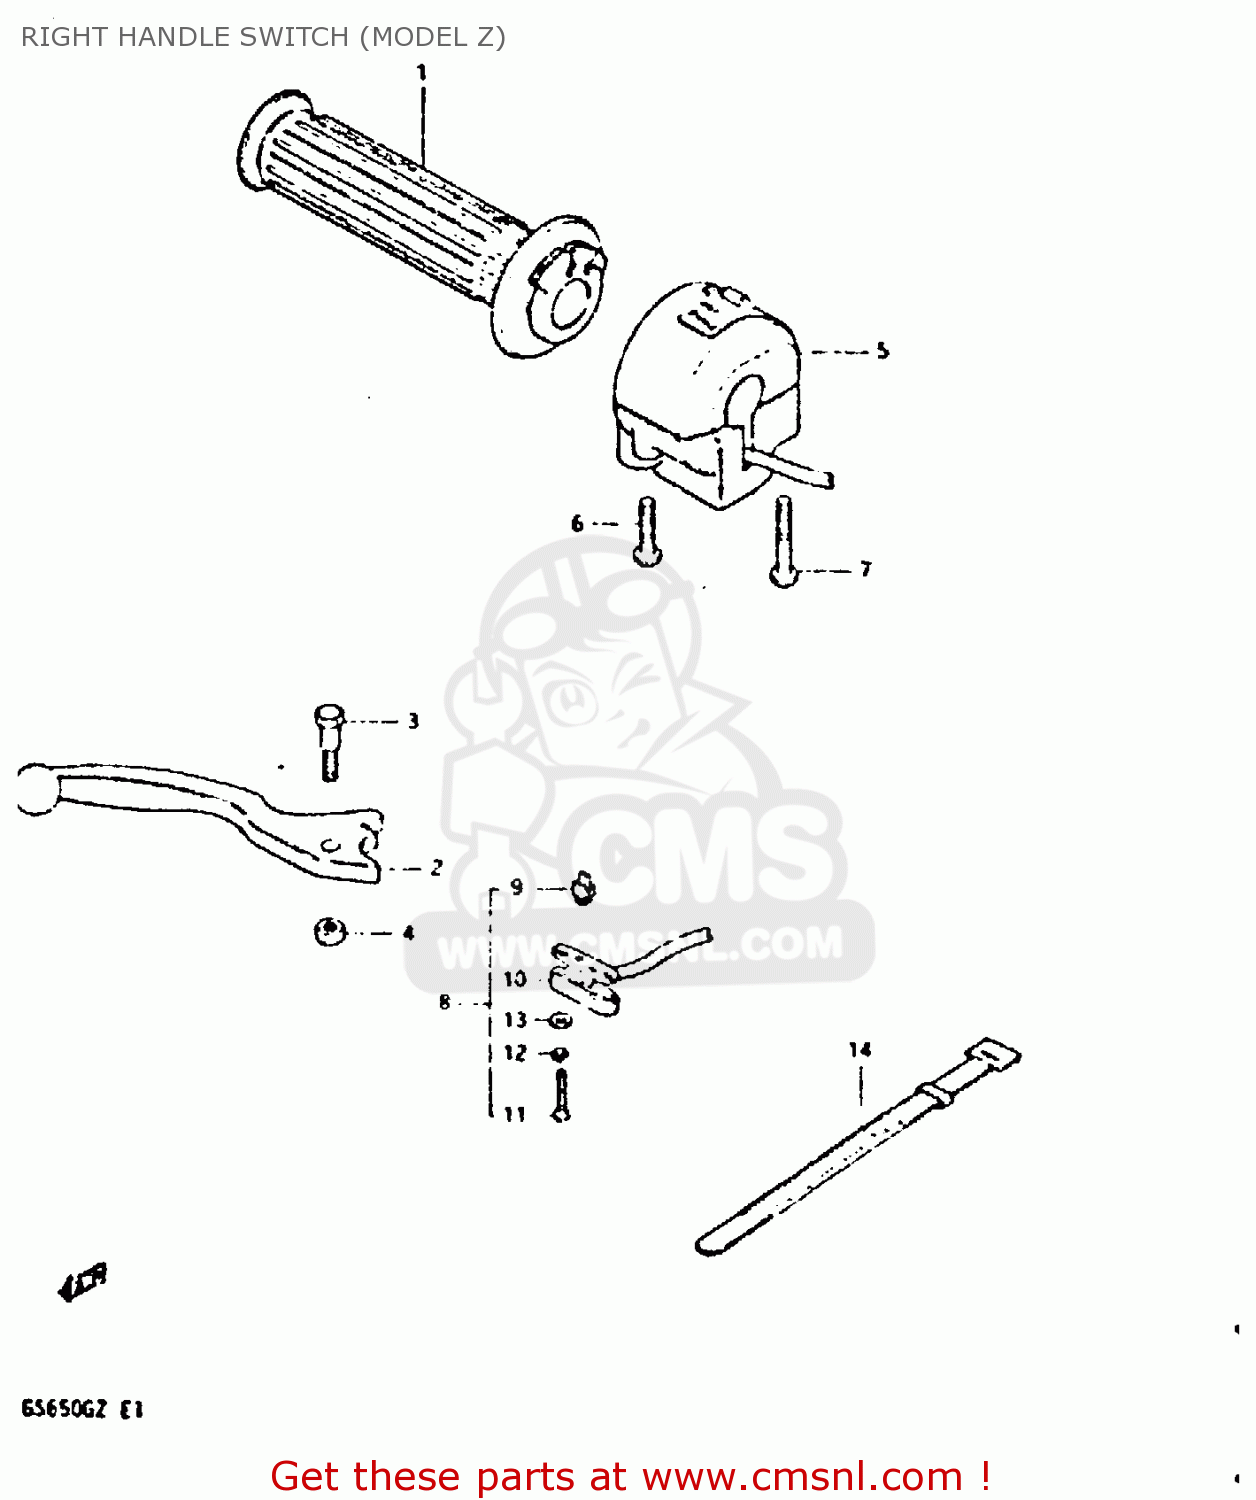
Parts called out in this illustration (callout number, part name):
1	GRIP,THROTTLE
2	LEVER,BRAKE
3	BOLT
4	NUT 6MM
5	SWITCH ASSEMBLY,HANDLE,RIGHT
6	SCREW
7	SCREW
8	SWITCH ASSEMBLY
9	CONTACT,SWITCH
10	COVER,FR BK TERMINAL BASE
11	SCREW
12	LOCK WASHER
13	WASHER
14	CLAMP(L:120)
